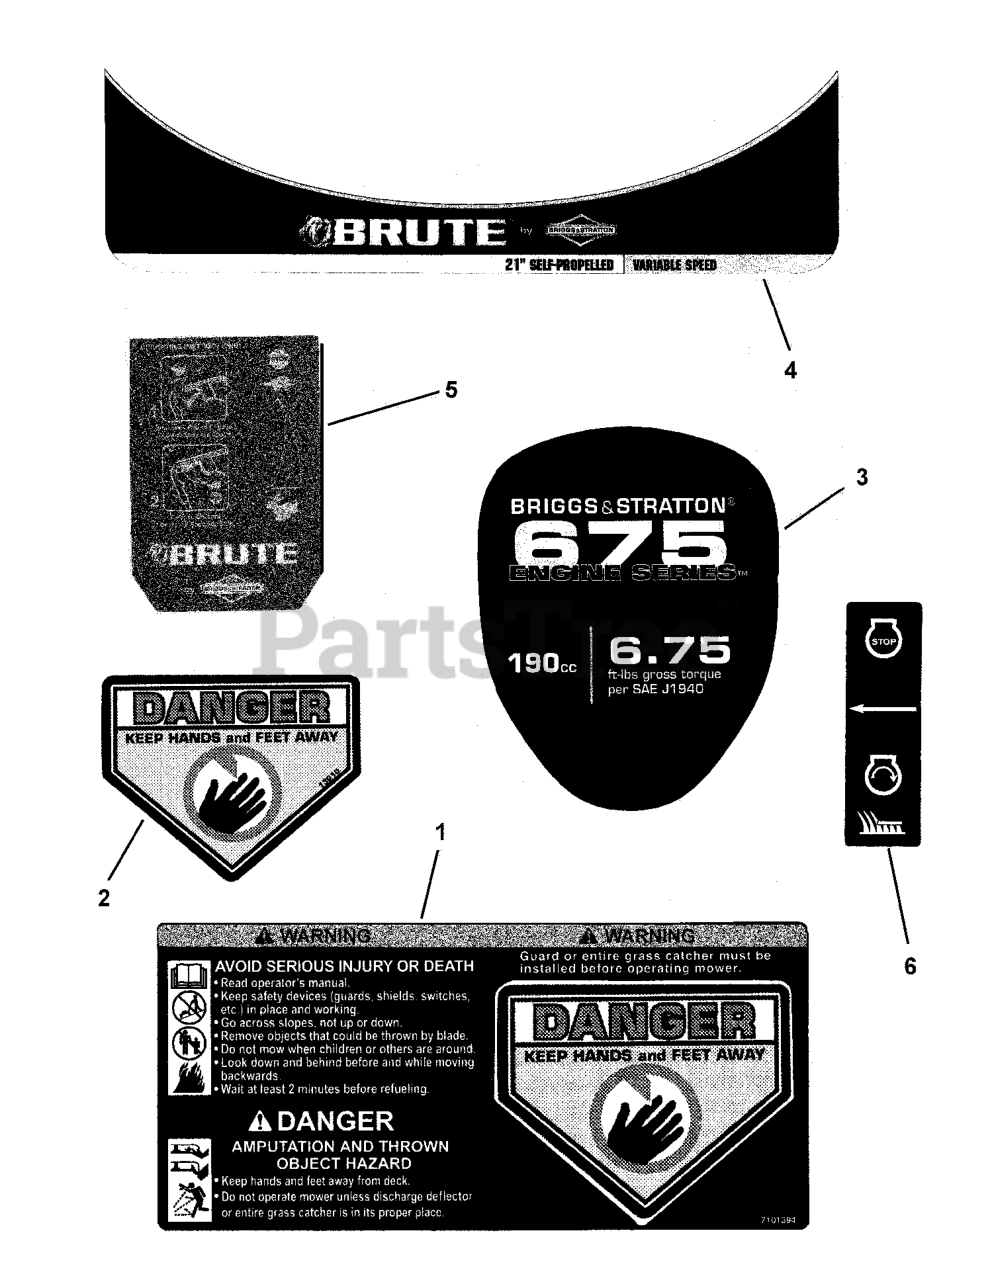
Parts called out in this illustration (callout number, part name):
1	DECAL, WARNING, REAR DISCHARGE DOOR
2	DECAL, DANGER, CUT FINGER
3	DECAL, ENGINE, TP, BRUTE 675
4	DECAL, DECK FRONT, 21" BRUTE, VS
5	DECAL, CONTROL HEAD 21" BRUTE
6	DECAL, OPC BAIL INTERNATIONAL SYMBOL
